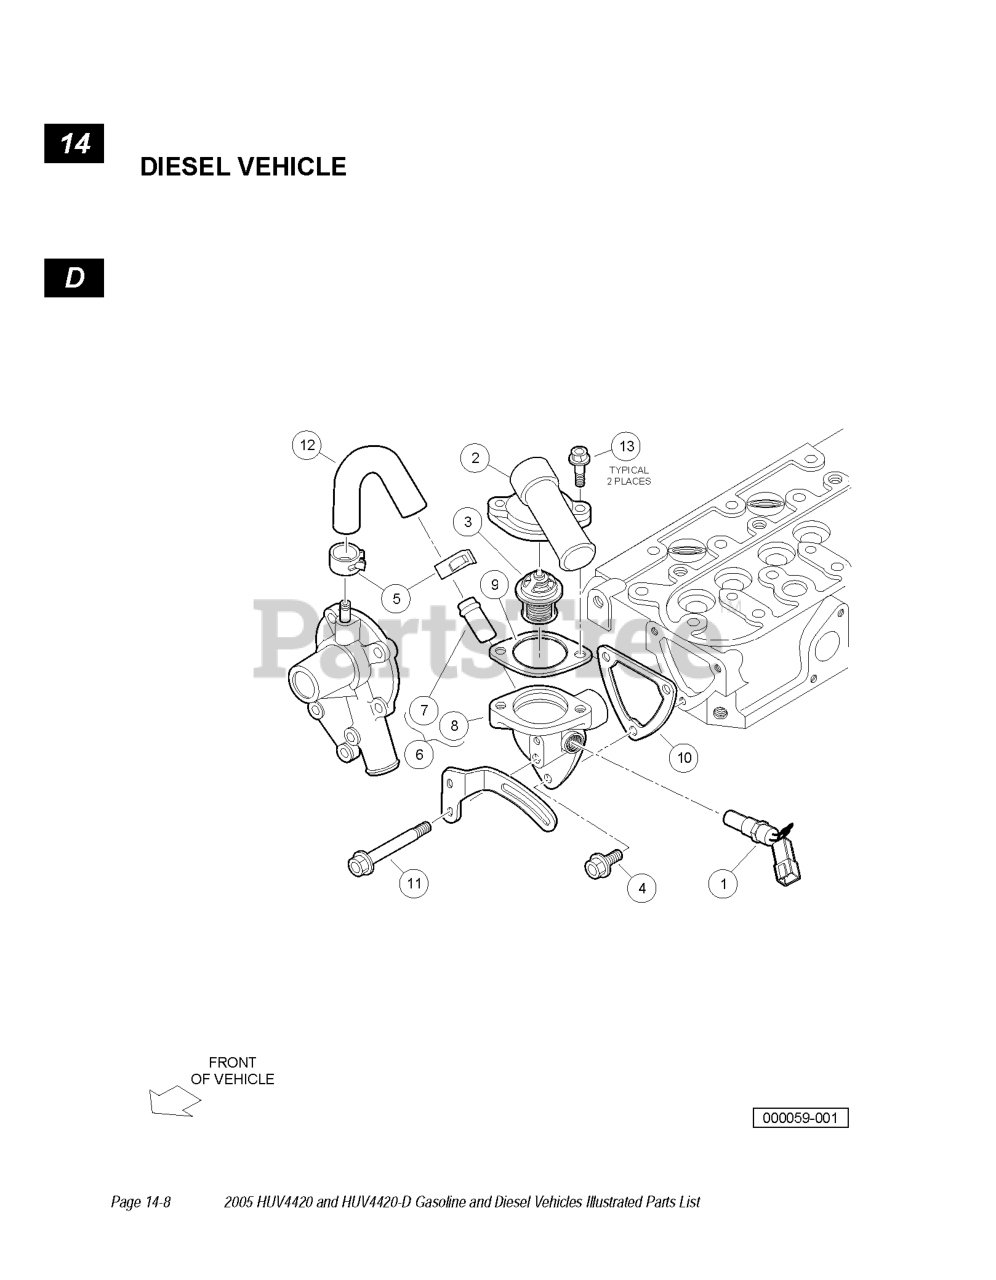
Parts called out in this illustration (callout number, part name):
1	SENSOR, COOLANT TEMP
2	COVER, THERMOSTAT
3	ASSY, THERMOSTAT
4	BOLT, M6X1X20
5	BAND, PIPE
6	COMP, FLANGE WATER
7	PIPE-BREATHER
9	GASKET, THERMOSTAT
10	GASKET, WATER FLANGE
11	BOLT, ALT, D722, STAY LOWER
12	PIPE, WATER RETURN, D722
13	Bolt, D722, Thermostat Cover
